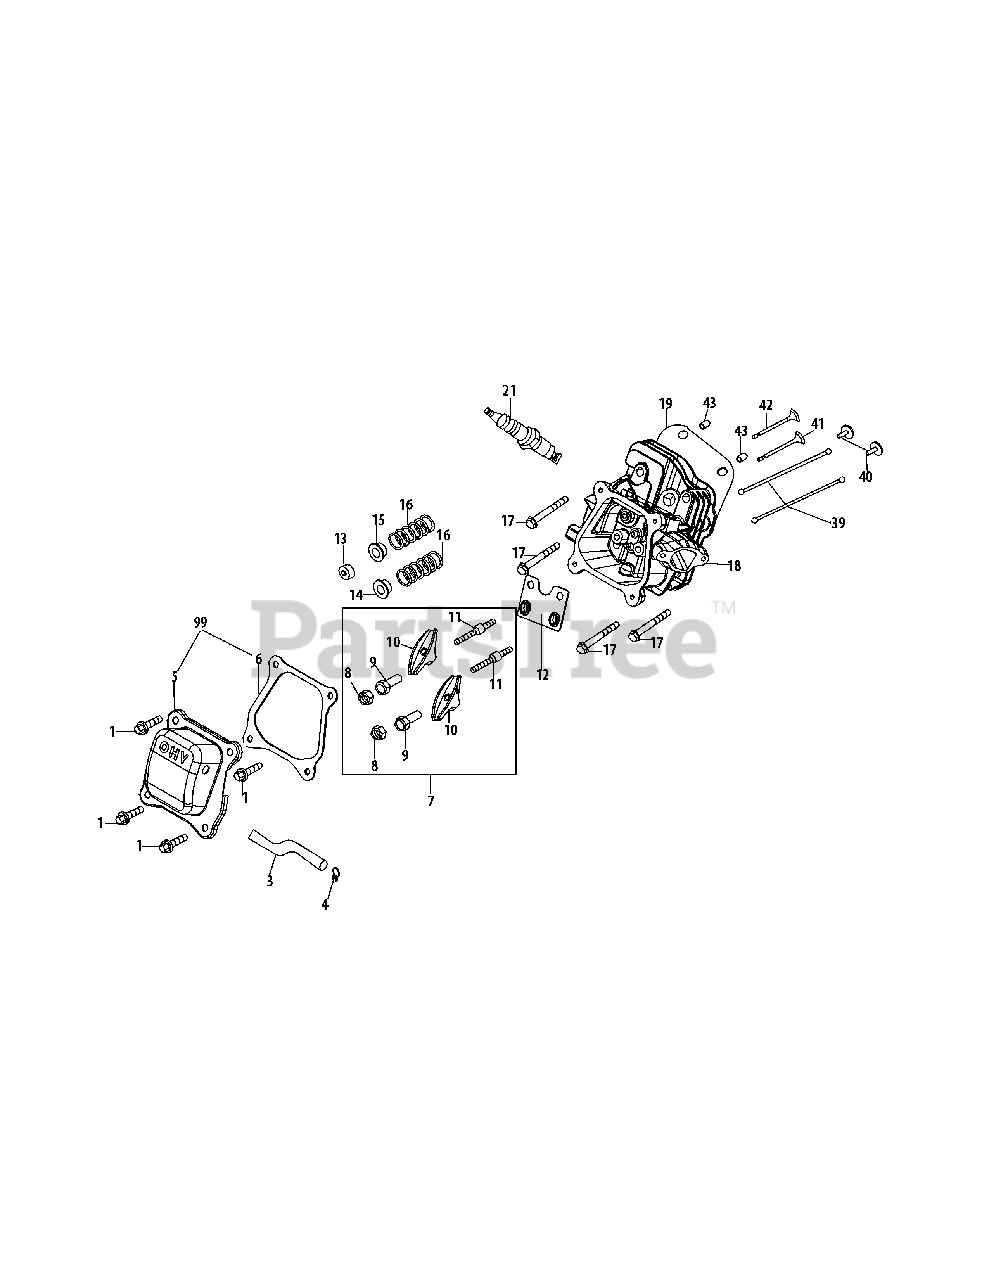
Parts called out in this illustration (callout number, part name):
1	Boltm6×16
3	Breather Hose
4	Breather Hose Clamp
5	Valve Cover
6	Valve Cover Gasket
7	Valve Rocker Arm And Bolt
8	Nut, Pivot Lock
9	Nut , Pivot
10	Rocker Arm
11	Stud, Rocker
12	Plate, Push Rod Guide
13	Adjuster, Ex. Valve
14	Intake Valve Retainer
15	Exhaust Valve Retainer
16	Spring, Valve
17	Bolt, Flange, 8×50
18	Cylinder Head Assembly
19	Gasket, Cylinder Head
21	Spark Plug
39	Push Rod Kit
43	Pin, Dowel, 10×16
